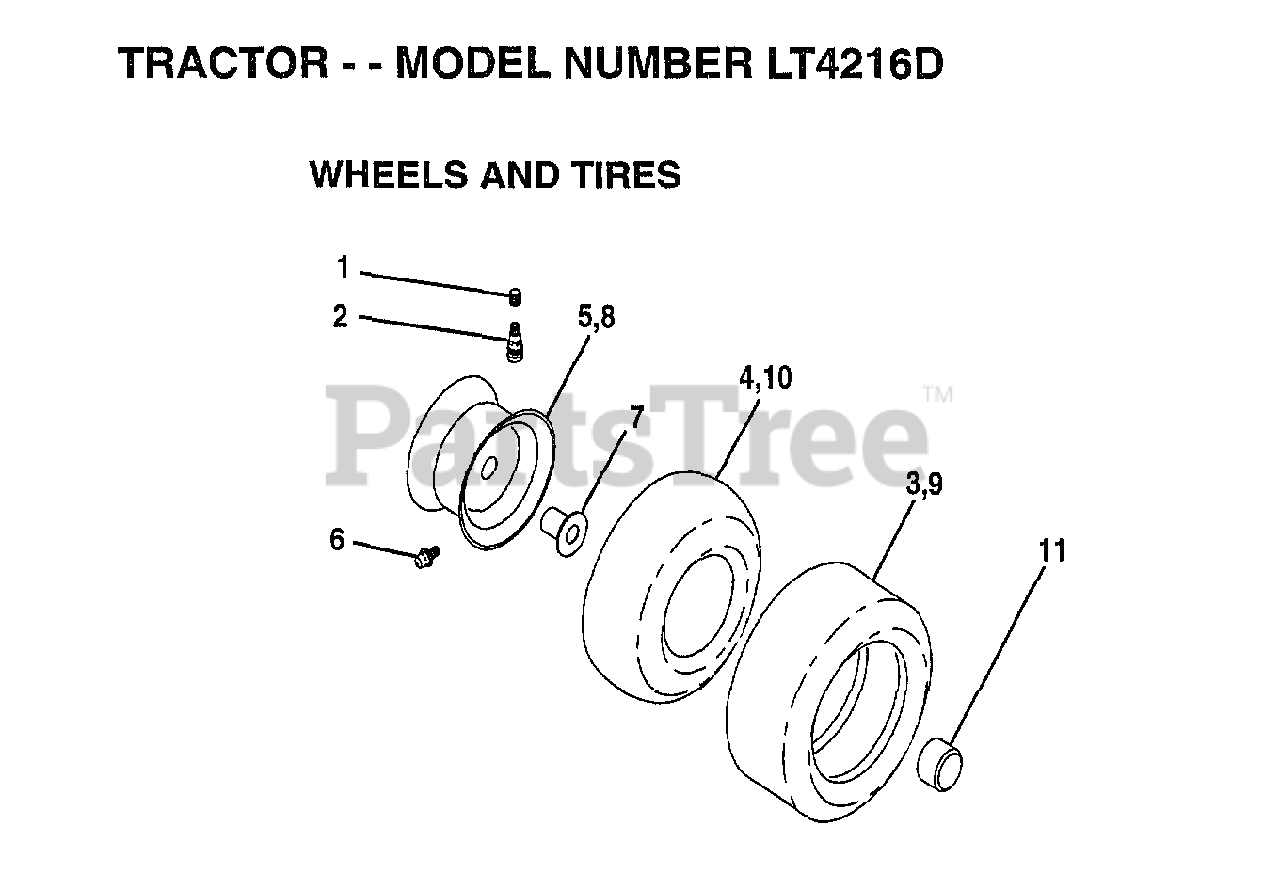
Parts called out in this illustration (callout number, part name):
1	VALVE CAP
2	VALVE STEM LT
4	TUBE.5.3/4.5/6
5	"RIM FRT 6"" ASM"
6	FITTING LT
7	"FLANGE, BEARING"
8	"RIM REAR 8"" ASM"
9	TIRE.20X8-8
10	TUBE.18X9.5-8
11	HUB CAP
